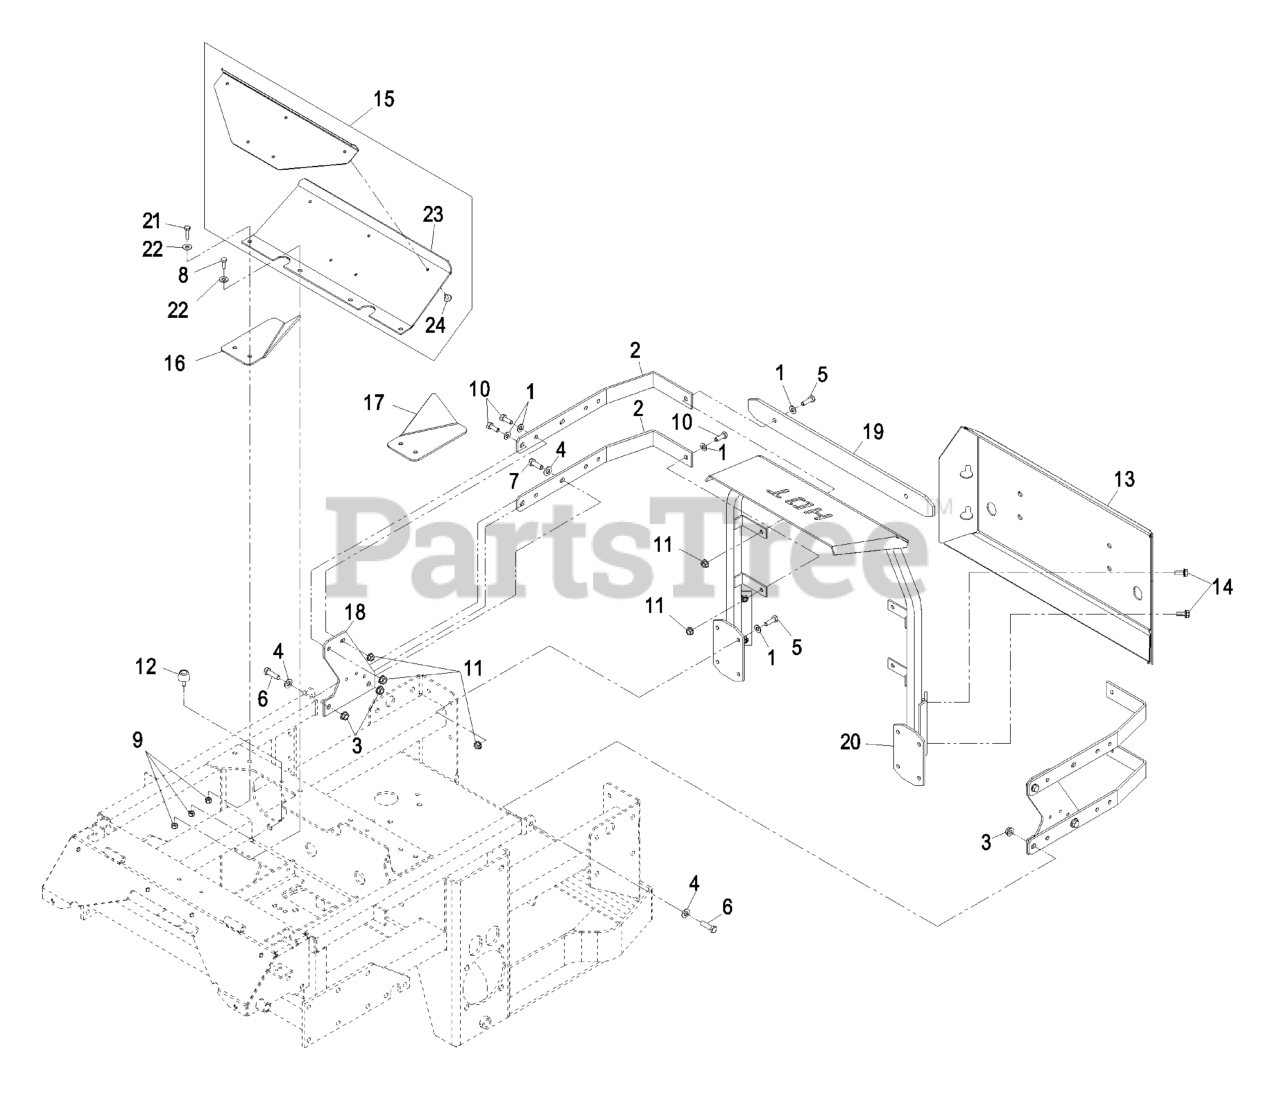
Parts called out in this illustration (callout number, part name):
1	WASHER-PLAIN
2	BAR-MOUNT FRAME, RADIATOR
3	NUT-HHF, WHIZ
4	WASHER-FLAT
5	SCREW-HH
6	SCREW-HH
7	SCREW-HH
8	SCREW-HH
9	NUT-LOCK, NI
10	SCREW-HH
13	WLD,REAR BUMPER
14	SCREW-HHF
15	KIT,FRNT ENG COVER W/DECA
16	SUPPORT-FRONT COVER, RH
17	SUPPORT-FRONT COVER, LH
18	Support, Rib Side
19	GUARD, XS REAR MUFFLER
20	WLD,AIR DEFLECTOR
21	SCREW-HH
22	WASHER-FLAT
24	RIVET-POP
